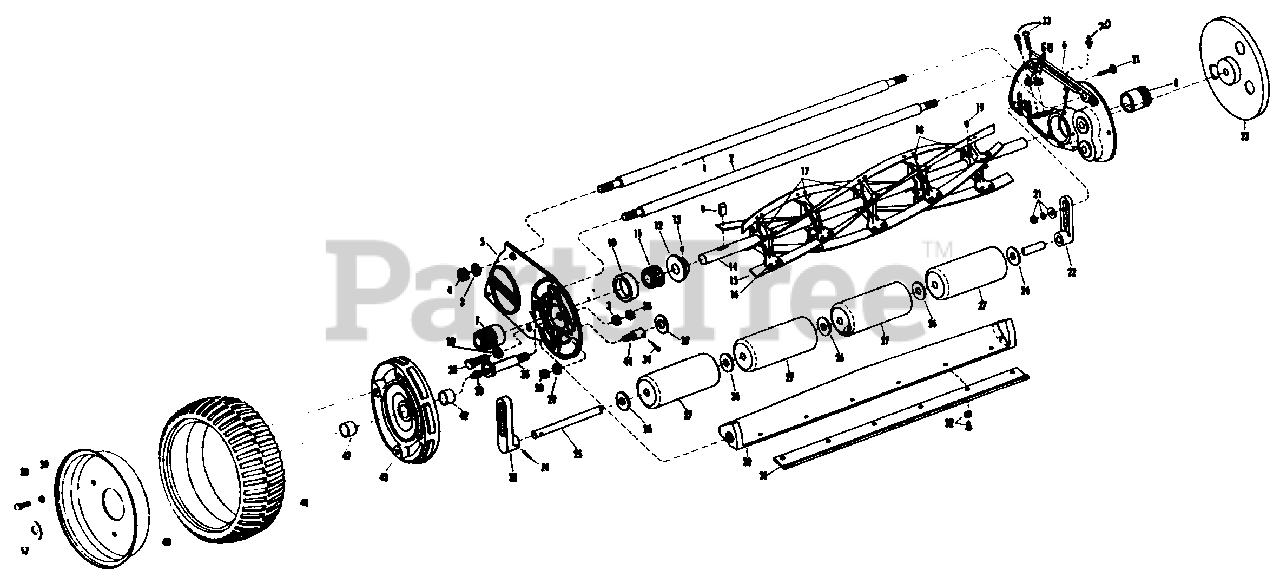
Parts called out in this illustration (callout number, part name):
1	Tie Rod for Rear
2	Tie Rod for Front
3	Lock Washer
5	Side Plate, R.H.
6	Side Plate, L.H.
7	Pinion, LH (From Front of Mower)
8	Pinion, RH (From Front of Mower)
10	Bearing Cup for Spiral Cutter
11	Bearing for Spiral Cutter
12	Collar for Spiral Cutter Shaft
13	Allen Set Screw for Collar
14	Shaft for Spiral Cutter
15	Knife for Spiral Cutter
16	Rivet for Spider
17	Spider, RH, for Spiral Cutter
18	Spider, LH, for Spiral Cutter
19	Set Screw for Spider
20	Zerk Grease Fitting
21	Bolt Assembly for Roller Bracket
22	Roller Bracket, R. or L.
23	Wheel Cover, RH
23	Wheel Cover, LH
24	Roll Pin for Roller Bracket
25	Shaft for Roller
26	Flat Washer for Roller
27	Wood Roller Section (4 Sectional)
28	Pivot Screw for Knife Bar
29	Lock Washer
30	Knife Bar
31	Lower Knife
32	Screw Assembly for Lower Knife
33	Adjusting Screw for Knife Bar
34	Cotter Pin
35	Wheel Stud Assy., w/Nut & Washers
36	Hex Nut for Wheel Stud
37	Flat Washer
38	Cap Screw for Wheel
39	Lock Washer for Wheel
40	Wheel 1/2 Section
41	Tire for Wheel
42	Bearing for Wheel (2 in ea. Wheel)
43	Hub and Gear for Drive Wheel
44	Stud for Tie Iron
50	Hex Nut for Tie Iron Stud
57	Flat Washer
58	Hex Nut, Jam, 3/8"-24
59	Lock Nut, 1/2"-13
